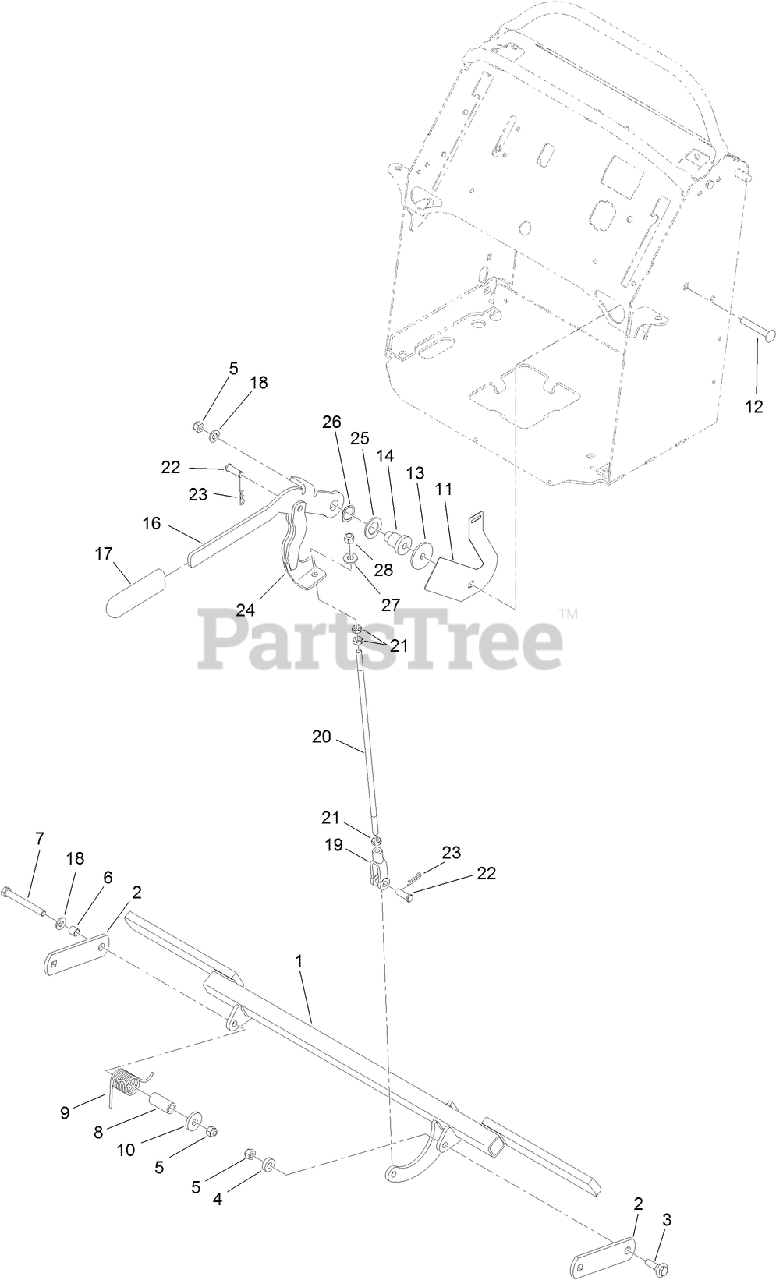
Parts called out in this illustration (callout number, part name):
1	BAR-BRAKE
2	SUPPORT-BRAKE
3	SCREW-SHOULDER, HWH
4	SPACER
5	NUT-HF, NI
6	SPACER
7	SCREW-HH
8	SPACER
9	SPRING-TORSION
10	WASHER
11	PLATE-SWITCH, BRAKE
12	SCREW-CARR
13	WASHER-REBOUND
14	MOUNT-PULLEY
16	LEVER-BRAKE
17	GRIP-LEVER
18	WASHER-FLAT
19	YOKE-LINKAGE, BRAKE
20	ROD-BRAKE
21	NUT-HJ
22	PIN-CLEVIS
23	PIN-COTTER
24	ARM-BRAKE
25	WASHER
26	Washer-Wave
27	WASHER-BELLEVILLE
28	NUT-LOCK
